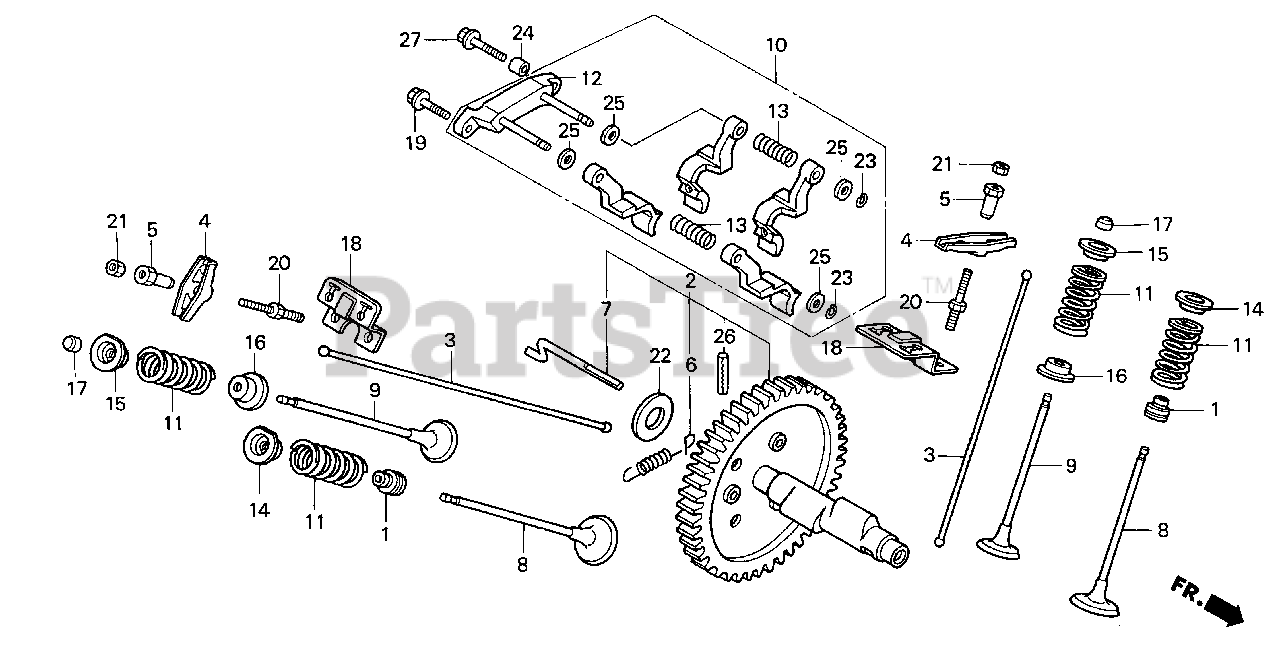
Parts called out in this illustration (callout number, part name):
1	SEAL, VALVE STEM
2	CAMSHAFT ASSY.
3	ROD, PUSH
4	ARM, VALVE ROCKER
5	PIVOT, ROCKER ARM
6	SPRING, WEIGHT RETURN
7	PIN, DECOMPRESSION
8	VALVE, IN.
9	VALVE, EX.
10	LIFTER ASSY., VALVE
11	SPRING, VALVE
12	SHAFT, VALVE LIFTER
13	SPRING, VALVE LIFTER
14	RETAINER, IN. VALVE SPRING
15	RETAINER, EX. VALVE SPRING
16	SEAT, VALVE SPRING
17	ROTATOR, VALVE
18	PLATE, PUSH ROD GUIDE
19	BOLT, FLANGE (5X16)
20	BOLT, PIVOT (8MM)
21	NUT, PIVOT ADJ.
22	WASHER, THRUST (17.2MM)
23	CLIP, GOVERNOR HOLDER
24	PIN A, DOWEL (8X12)
25	WASHER, PLAIN (6MM)
26	PIN, SPRING (6X28)
27	BOLT, FLANGE (6X25)
